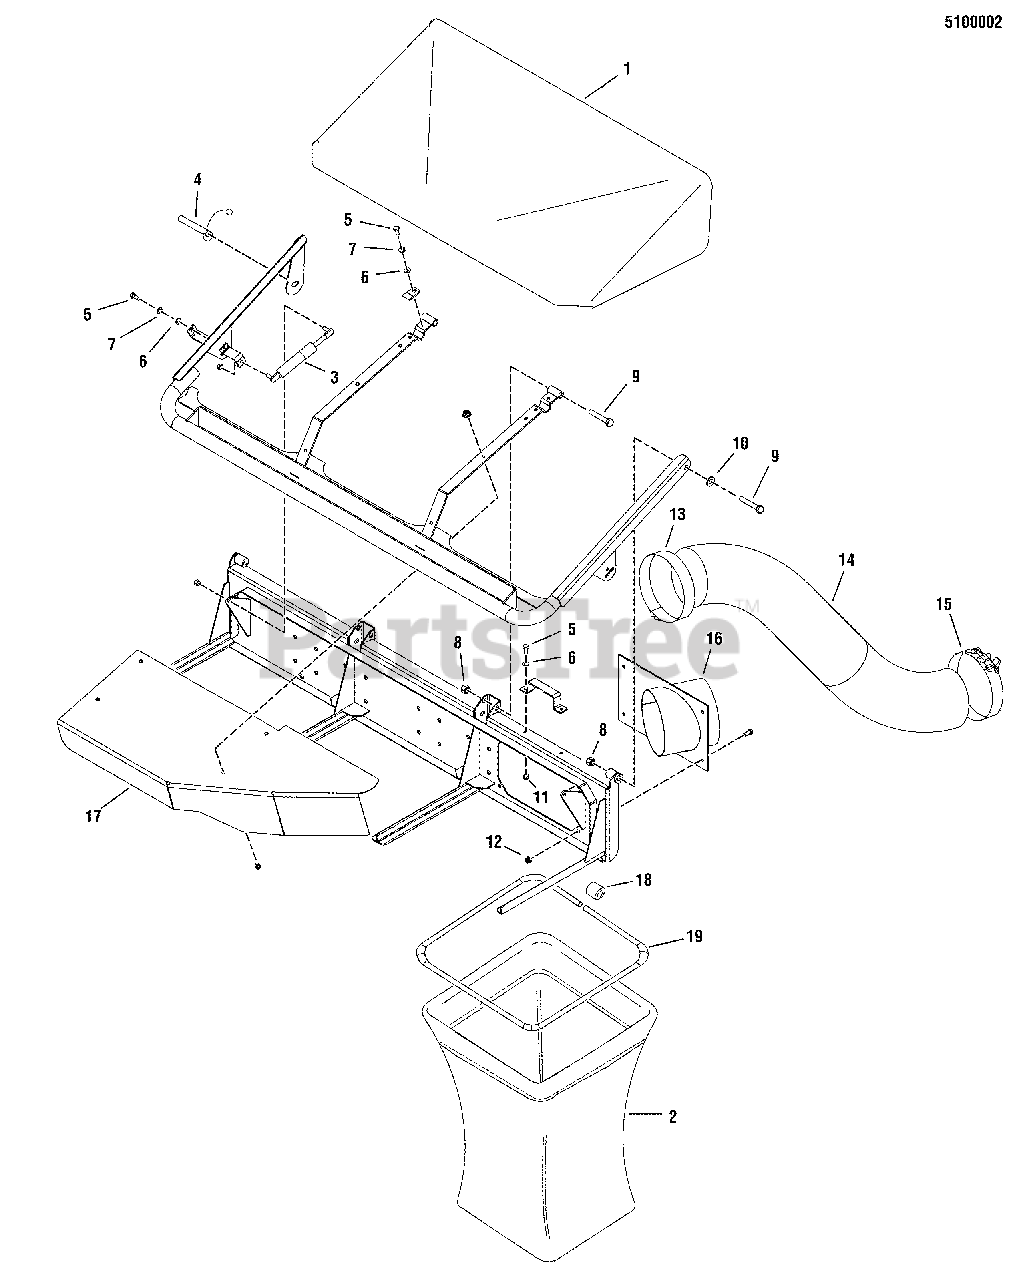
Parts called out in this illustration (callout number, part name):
1	3 BAG AIR DOME
2	CATCHER BAG W/ HANDLE
3	GAS CYLINDER
4	DETENT PIN W/ LANYARD
5	BOLT, 5/16-18 X 3/4 GD5
6	WASHER, 5/16" SAE
7	WASHER, 5/16 LOCK CZ
8	NUT, 1/2-13 HEX NYLON LOCK
9	BOLT, 1/2-20 X 3" GD5
10	WASHER, 1/2 SAE
11	NUT, 5/16-18 HEX NYLON LOCK
12	NUT, 5/16-18 HEX NYLOCK FLANGE
13	CLAMP, HOSE, UPPER
14	HOSE, FLEXIBLE, 7" DIA. X 58"
15	CLAMP, HOSE, LOWER
16	WELD, INLET BLOWER 3-BAG BLACK
18	BAG FRAME CONNECTOR, PLASTIC
19	BAG FRAME
